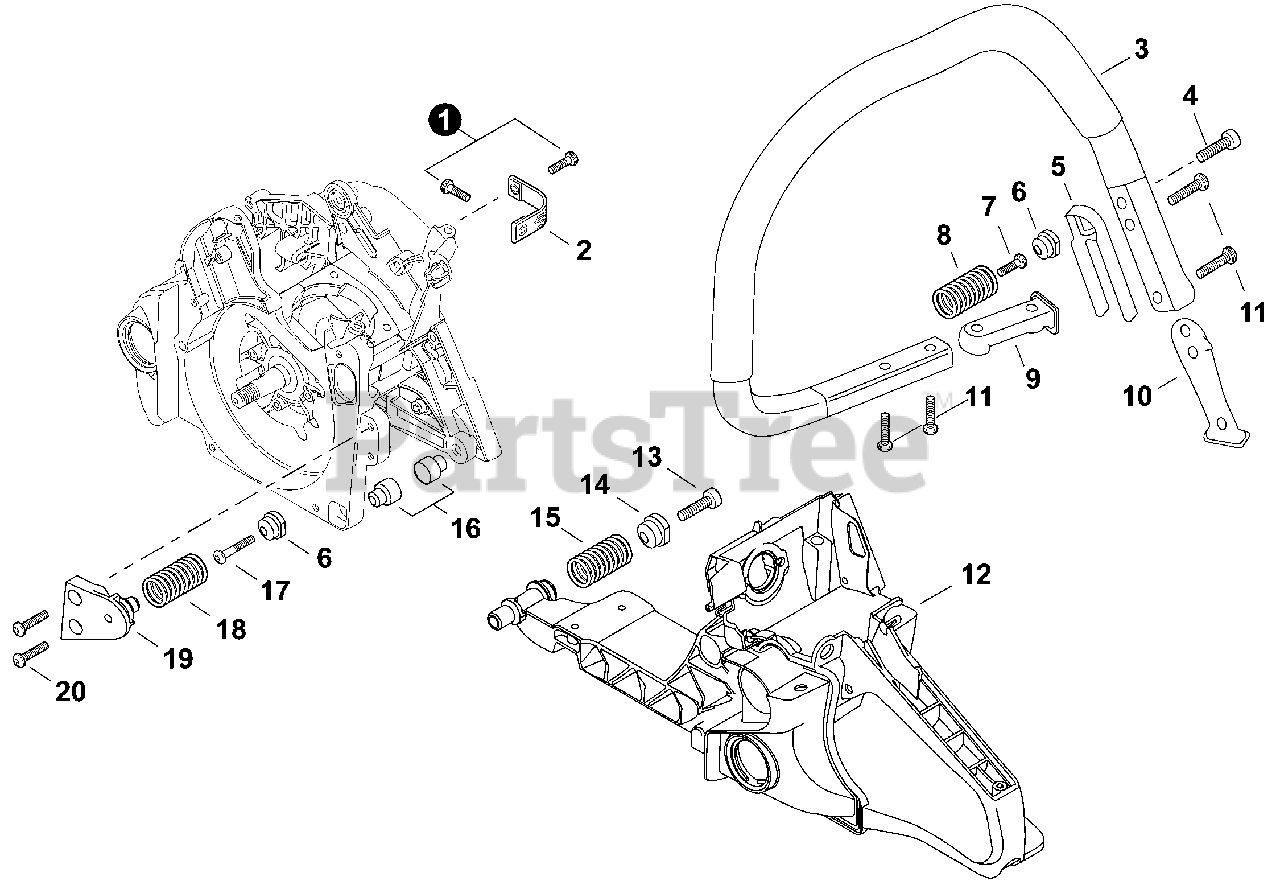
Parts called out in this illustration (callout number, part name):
1	BOLT, TORX 5×16
2	STRAP, SAFETY
3	HANDLE, FRONT
4	BOLT, TORX 6×20
5	HOLDER, SPRING
6	HOLDER, SPRING Ø14.4
7	BOLT, TORX 5×16
8	SPRING, COMPRESSION Ø17×38.4×2.6
9	MOUNT, HANDLE
10	MOUNT, HANDLE
11	BOLT, TORX 5×20
12	HANDLE, REAR
13	BOLT, TORX 6×20
14	HOLDER, SPRING Ø17
15	SPRING, COMPRESSION Ø20×40×3.3
16	CUSHION
17	BOLT, TORX 5×25
18	SPRING, COMPRESSION Ø17×36.7×2.6
19	HOLDER, SPRING
20	BOLT, TORX 5×20
